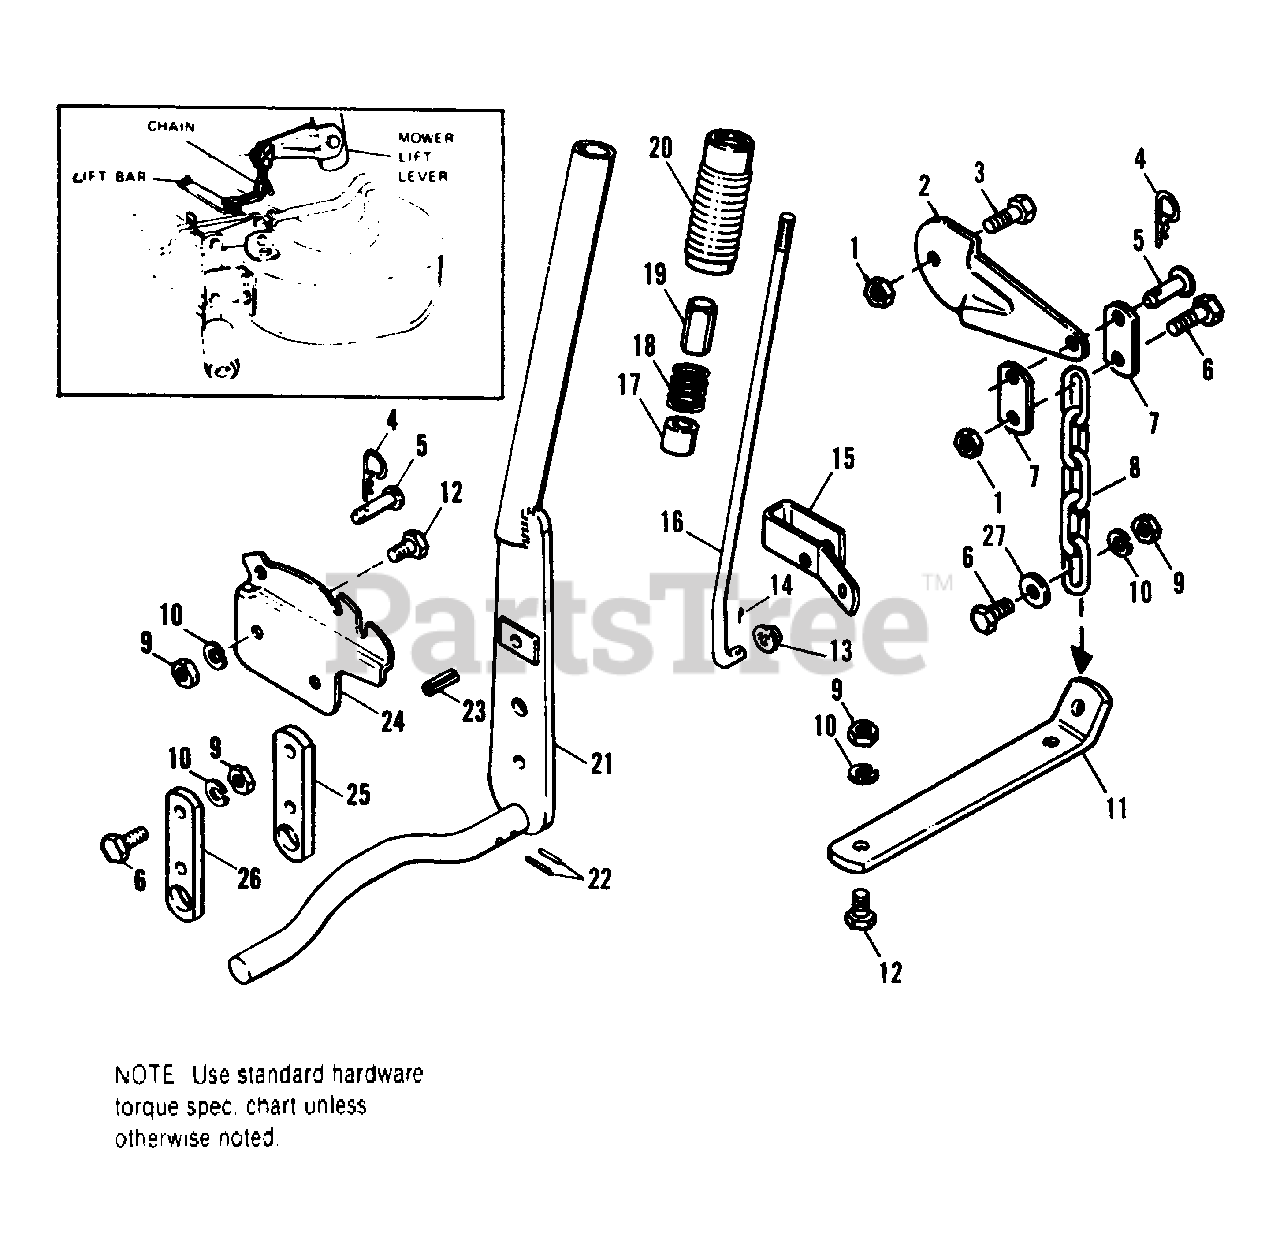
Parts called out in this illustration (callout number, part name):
1	LOCKNUT, Hex, 3/8-16
2	LEVER, Lift
3	CAPSCREW, Hex Hd., 3/8-16 x 7/8
4	CLIP, Spring
6	CAPSCREW, Hex Hd., 3/8-16 x 1
7	LINK, Mower Lift
8	CHAIN
9	NUT, Hex, Full, 3/8-16
10	LOCKWASHER, 3/8
11	BAR, Lift
12	CAPSCREW, Hex Hd., 3/8-16 x 3/4
14	PIN, Cotter, 3/32 x 3/4 (990485 Only)
15	LATCH, Lift Lever
16	ROD, Lift Lever
16	ROD, Lift Lever (990485 Only)
19	BUTTON, Thumb
20	GRIP, Handle
21	LEVER ASSY., Lift
22	PIN, Roll, 3/16 x 1
23	PIN, Roll, 3/8 x 1
25	BAR, Bearing, R.H.
26	BAR, Bearing, L.H.
27	WASHER, Plain, 3/8
